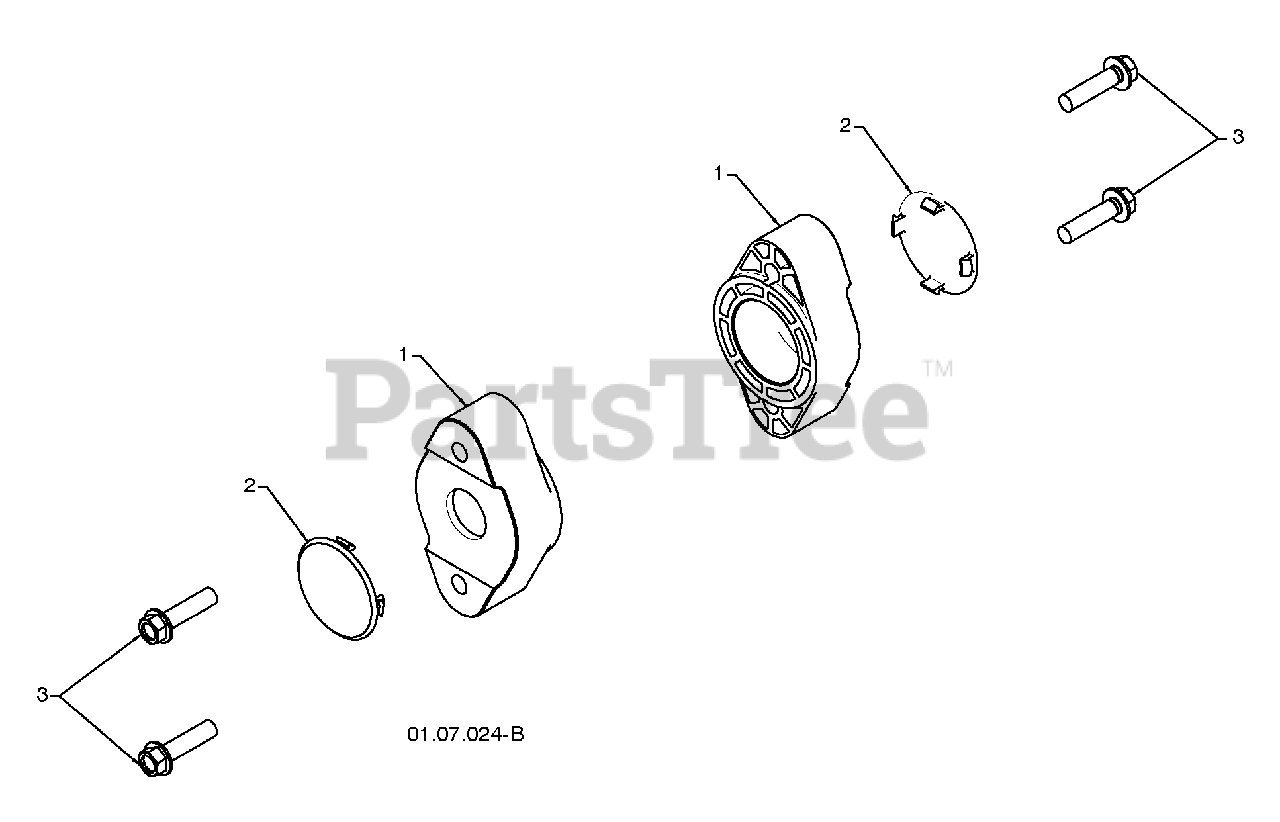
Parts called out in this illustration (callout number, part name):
1	AUGER BEARING
2	BEARING PLUG
3	SCREW 5/16-18 X 1.00
